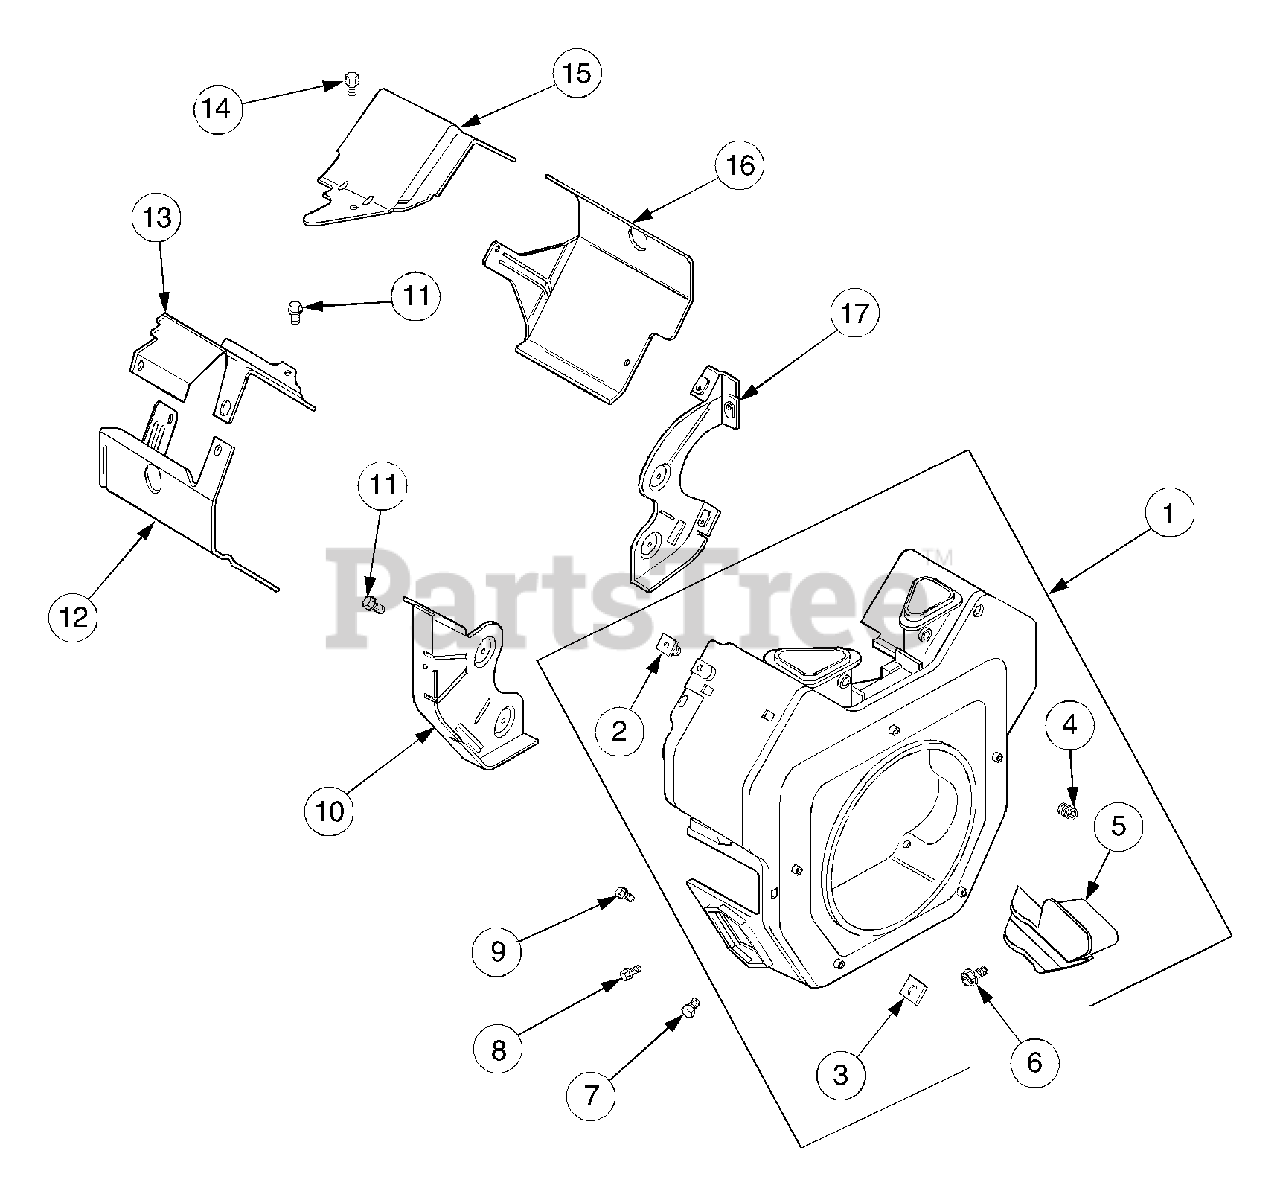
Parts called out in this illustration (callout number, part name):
1	Housing, Blower
2	Nut, Plastic
3	Plug, Button
4	Nut, Plastic
5	Cover, Blower Housing
6	Screw, Tapping
7	Screw, Hex Flange, M5 x 0.8 x 16
8	Screw, Hex Flange, M5 x 0.8 x 16
9	Screw, Hex Flange, M5 x 0.8 x 20
10	Plate, Backing - #2 Side
11	Screw, Hex Flange, M6 x 1.0 x 16
12	Baffle, Cylinder Barrel - #2 Side
13	Baffle, Valley - #2 Side
14	Screw, Hex Flange, M5 x 0.8 x 10
15	Baffle, Valley - #1 Side
16	Baffle, Cylinder Barrel - #1 Side
17	Plate, Backing - #1 Side
